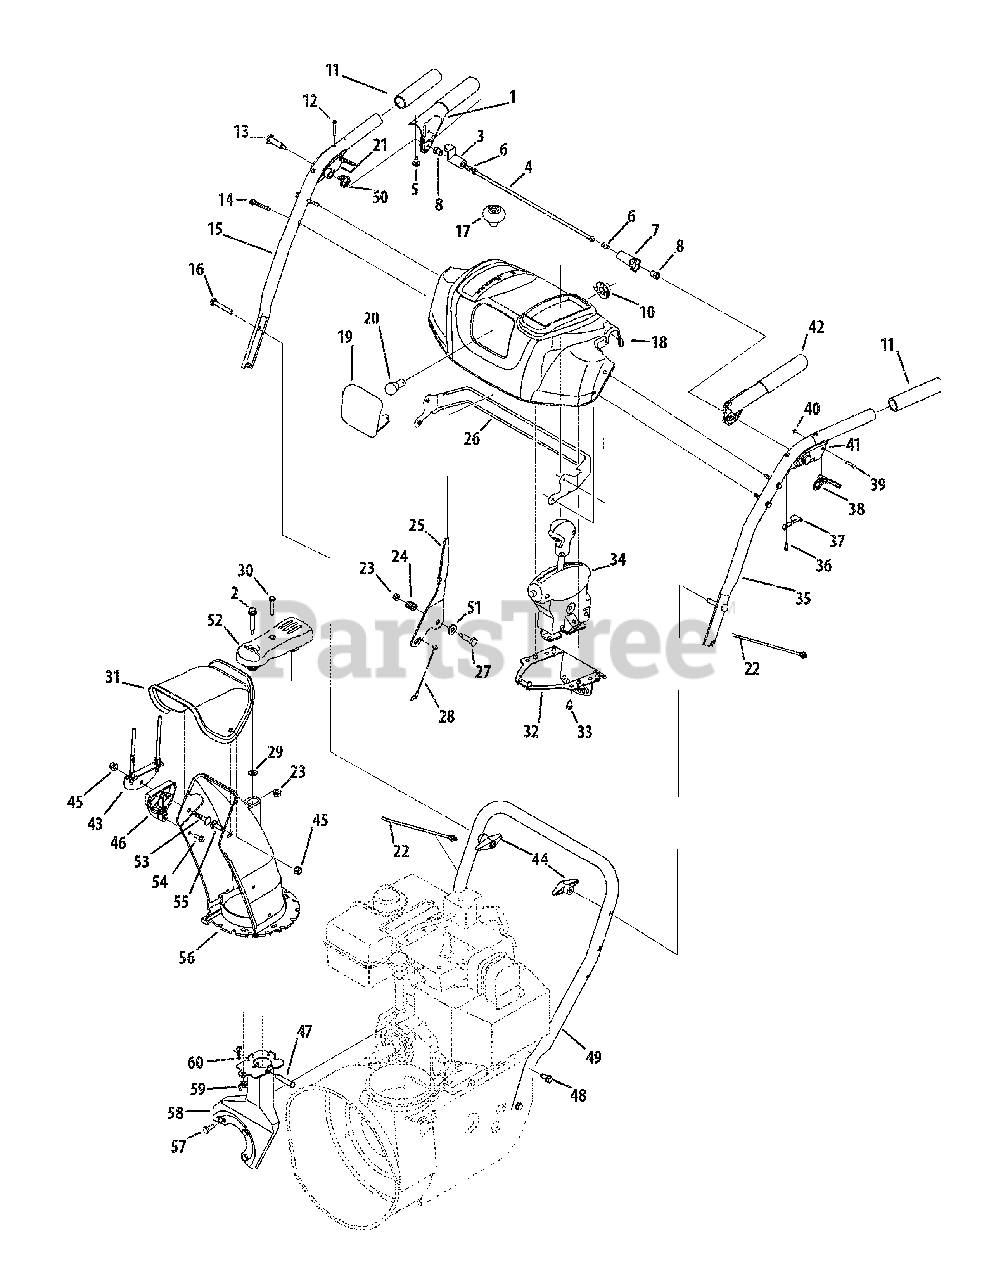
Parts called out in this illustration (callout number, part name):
1	Handle Engagement Assembly RH
2	Flange Shoulder Screw
3	Lock Plate
4	Pivot Rod
5	Rubber Bumper
6	Screw, 1/4-20 x.375
7	Clutch Lock Cam
8	Shoulder Nut, 1/4-20
10	Light Socket
11	Handle Grip
12	Screw, #10-24 x 0.375
13	Shoulder Screw, 1/4-20 x 1.345
14	Screw, 1/4-20 x 1.625
16	Carriage Screw, 5/16-18 x 2.25
17	Shift Knob
18	Handle Panel (Includes Ref. #19)
21	Handle Clutch Lock - RH
22	Cable Tie
23	Flange Lock Nut, 1/4-20
24	Compression Spring
25	Shift Lever
26	Panel Bracket
27	Shoulder Screw
28	Speed Selector Cable
29	Flat Washer, .25 x .630 x .0515
30	Screw, #10-16 x .500
31	Upper Chute
32	Joystick Bracket
33	Hi-Lo Screw, 1/4-15 x 0.5
34	4 Way Chute Control Assembly Service Kit
36	Screw, #8-16 x 0.50
37	Clutch Lock Spring
38	Steering Control
39	Pin, 3/16
40	E Ring
41	Handle Clutch Lock - LH
42	Handle Engagement Assembly LH
44	Wing Knob
45	Flange Lock Nut, 5/16-18
46	Chute Tilt Cable Guide
47	Clevis Pin
48	Hex Screw
50	Torsion Spring
51	Flat Washer
52	Joystick Pulley Cover
53	Carriage Bolt, 5/16-18 x 1.50
54	Hi-Lo Screw, 1/4-15 x .75
55	Carriage Bolt, 5/16-18 x 1.0
56	Lower Chute
57	Hex Screw, 5/16-24 x .750
58	Support Bracket
59	Wing Nut, 1/4-20
60	Bow Tie Cotter Pin
